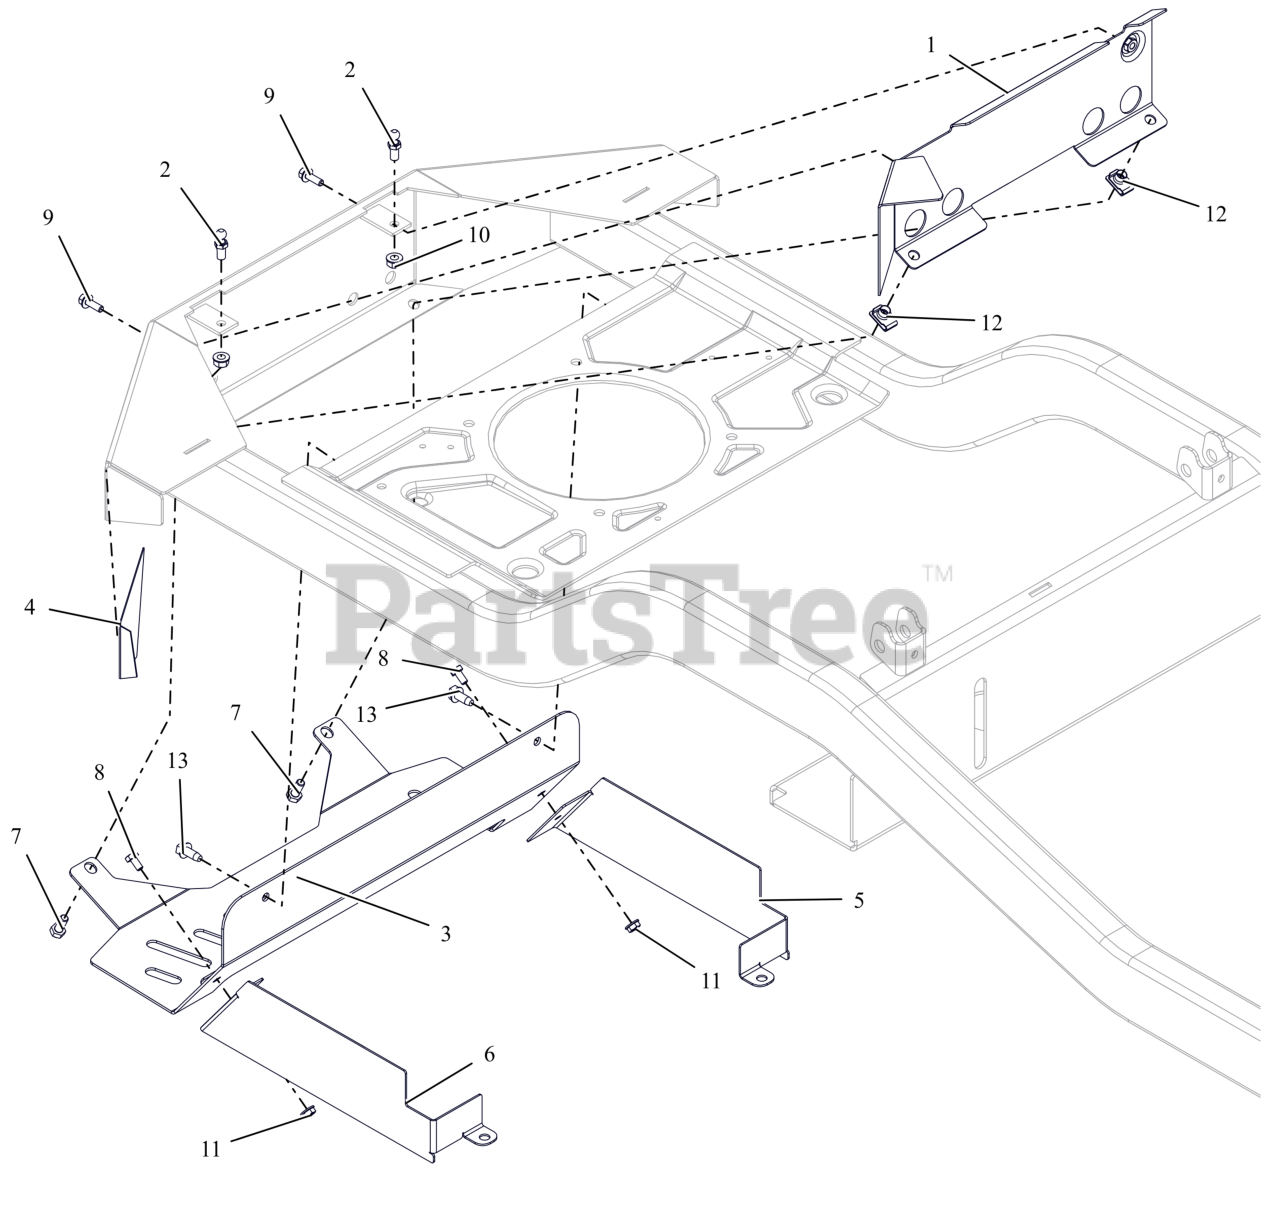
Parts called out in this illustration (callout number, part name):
1	WMT, HEAT BAFFLE
2	STUD- BALL
3	SHIELD, HEAT (HD)
4	TAPE, HEAT DEFLECTOR
5	GUARD,REAR CLUTCH LH
6	GUARD,REAR CLUTCH RH
7	BLT,HEX .31-18X.75 G5 ZCC
8	BLT,HEX .25-20X.50 G5 ZCC
9	BLT,HEX-FLG .25-20X.75 G5 BFP
10	NUT,LK-CTR-FLG .31-18 GF ZCC
11	NUT-LK-TOP-FLG .250-20 GF ZCC
12	NUT-CLIP RETAINER 5/16-18X.56
13	SCR,TAP .312-18X.75 HWH TR ZCC
